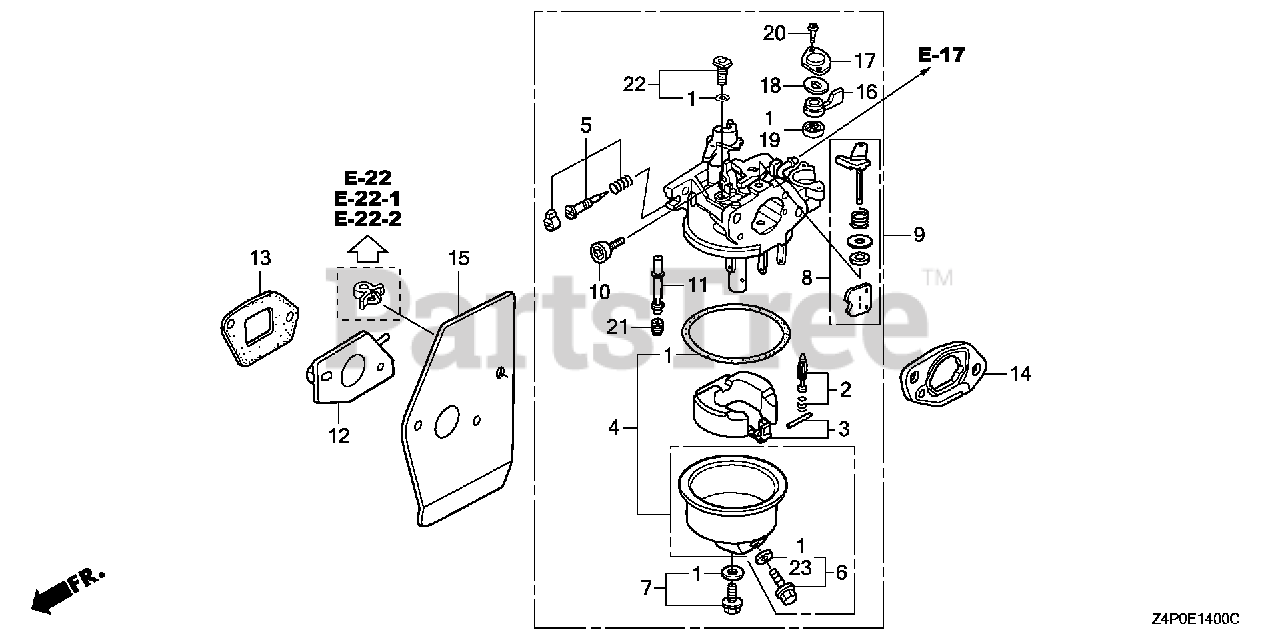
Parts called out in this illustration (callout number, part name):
1	GASKET SET (CARBURETOR NO.)
2	VALVE SET, FLOAT (SEAT NOT INCLUDED)
3	FLOAT SET (CARBURETOR NO.)
4	CHAMBER SET, FLOAT (CARBURETOR NO.)
5	SCREW SET, PILOT
6	SCREW SET, DRAIN (CARBURETOR NO.)
7	SCREW SET
8	CHOKE SET (CARBURETOR NO.)
9	CARBURETOR ASSY. (BE66N A)
9	CARBURETOR ASSY. (BEA2C A)
10	SCREW, THROTTLE STOP
11	NOZZLE, MAIN (CARBURETOR NO.)
12	INSULATOR, CARBURETOR
13	GASKET, INSULATOR
14	SPACER, CARBURETOR
15	GASKET, CARBURETOR
16	LEVER, PETCOCK
17	PLATE, LEVER SETTING
18	SPRING, PETCOCK LEVER
19	GASKET, PETCOCK
20	SCREW, PAN (3X6)
21	JET, MAIN (#62)
21	JET, MAIN (#65)
21	JET, MAIN (#68)
22	JET SET, PILOT (#35)
